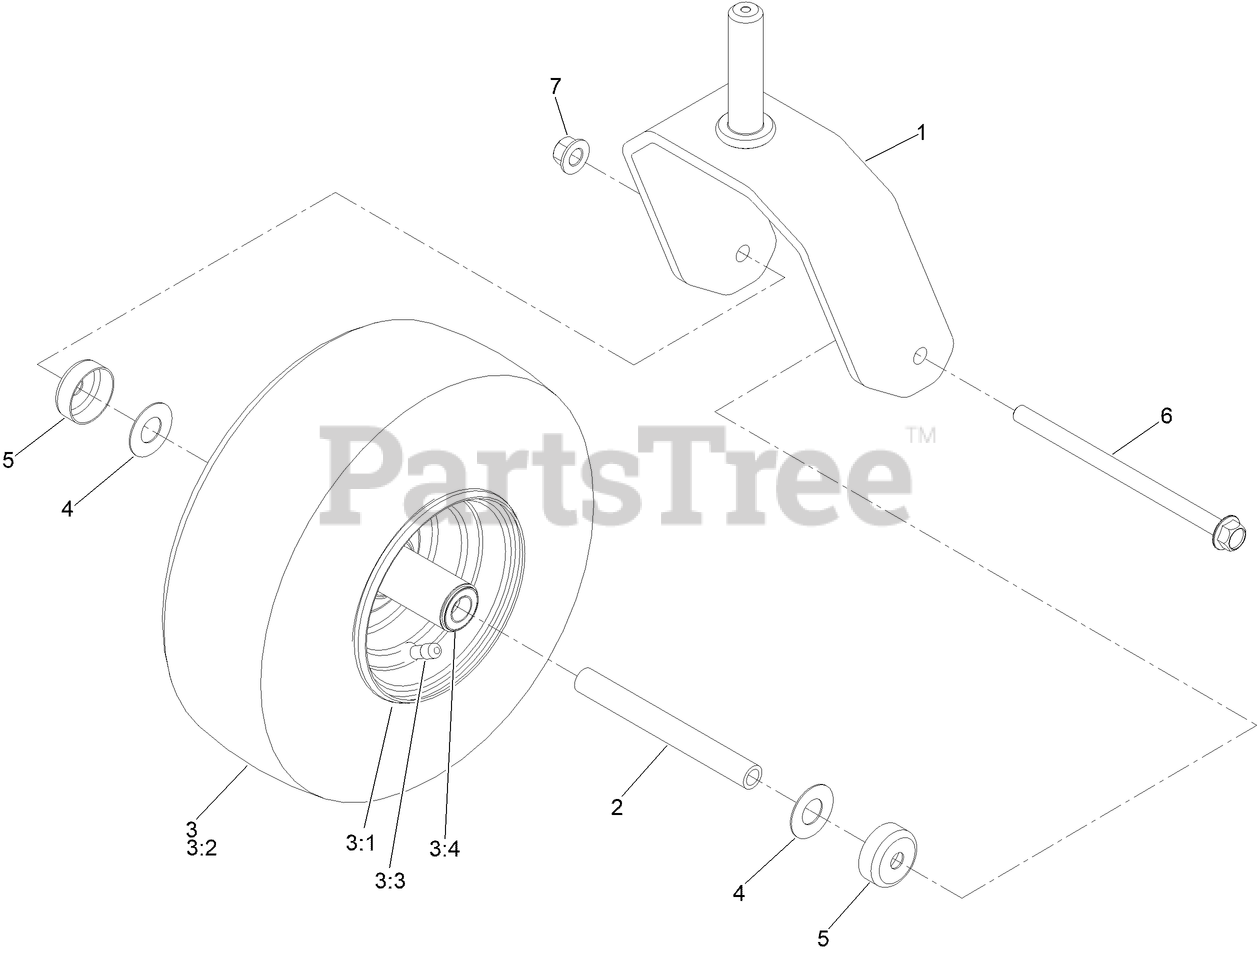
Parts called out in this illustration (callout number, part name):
1	CASTER-FORK [RED]
2	SPANNER-WHEEL
3	TIRE AND WHEEL ASM
3:1	RIM-6"
3:4	BEARING
4	WASHER
5	GUARD-SEAL
6	SCREW-HHF
7	NUT-LOCK
